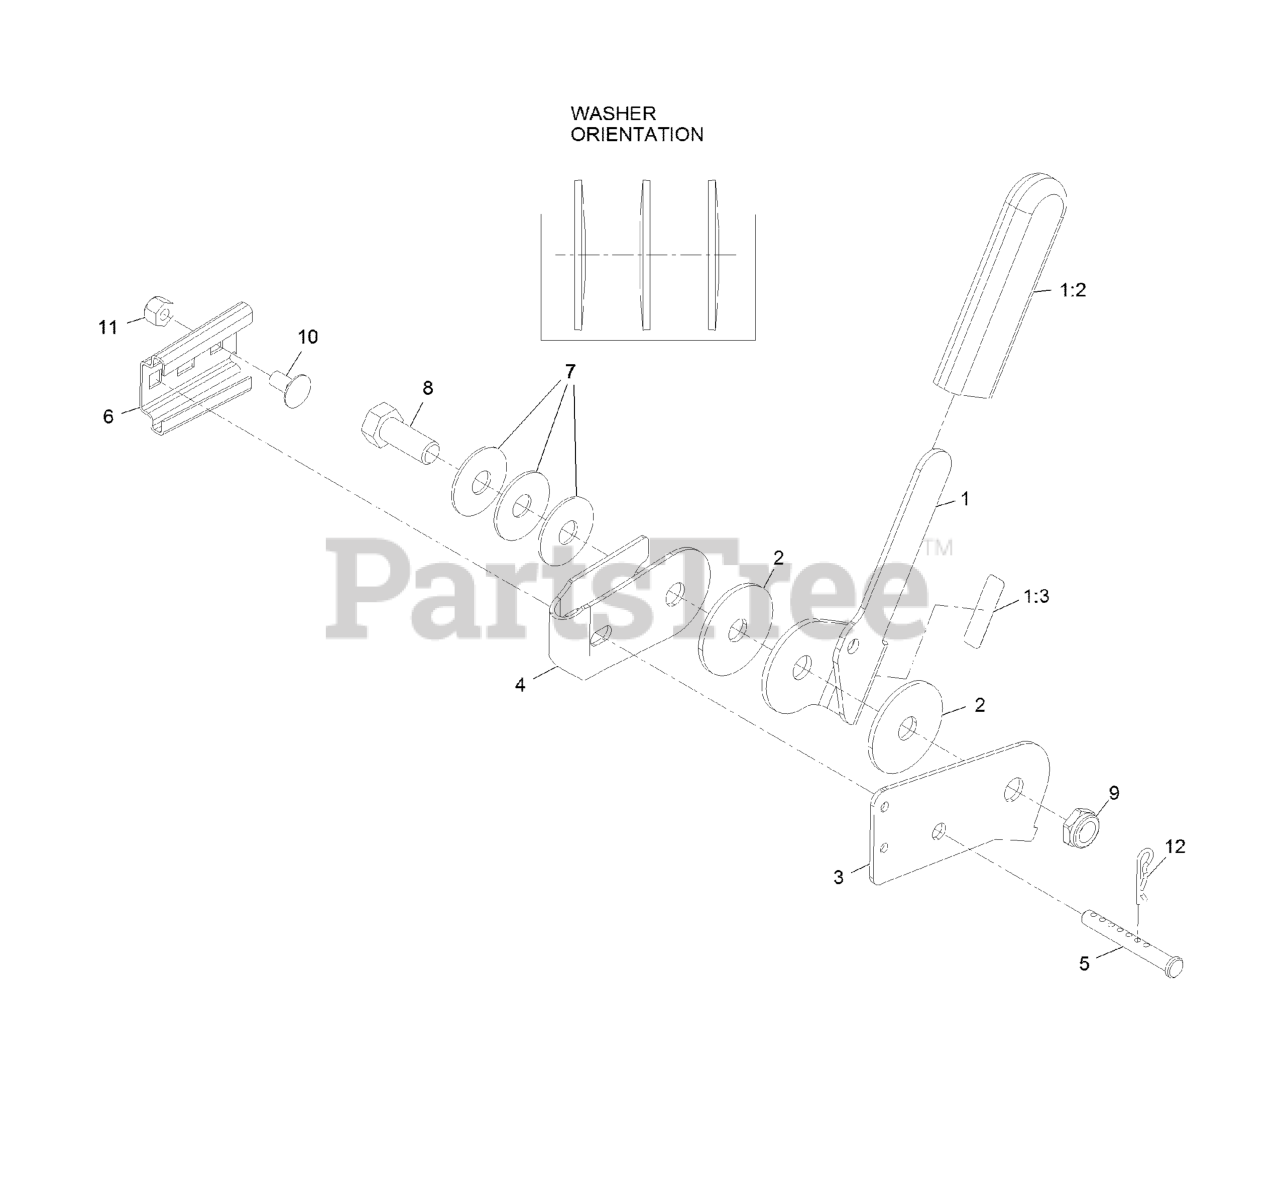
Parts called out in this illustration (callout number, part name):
1	CONTROL HANDLE ASM-OCD
1:2	GRIP-LEVER
1:3	Decal-Operation
2	DISC-FRICTION
3	BRACKET,CONTROL MOUNT
4	BRACKET,HANDLE MOUNT
5	PIN-CLEVIS
6	BRACKET-MOUNTING,SMV
7	WASHER-DISC, SPRING
8	SCREW-HH
9	NUT-HEX
10	SCREW-CARR
11	NUT-LOCK, NI
12	PIN-COTTER
